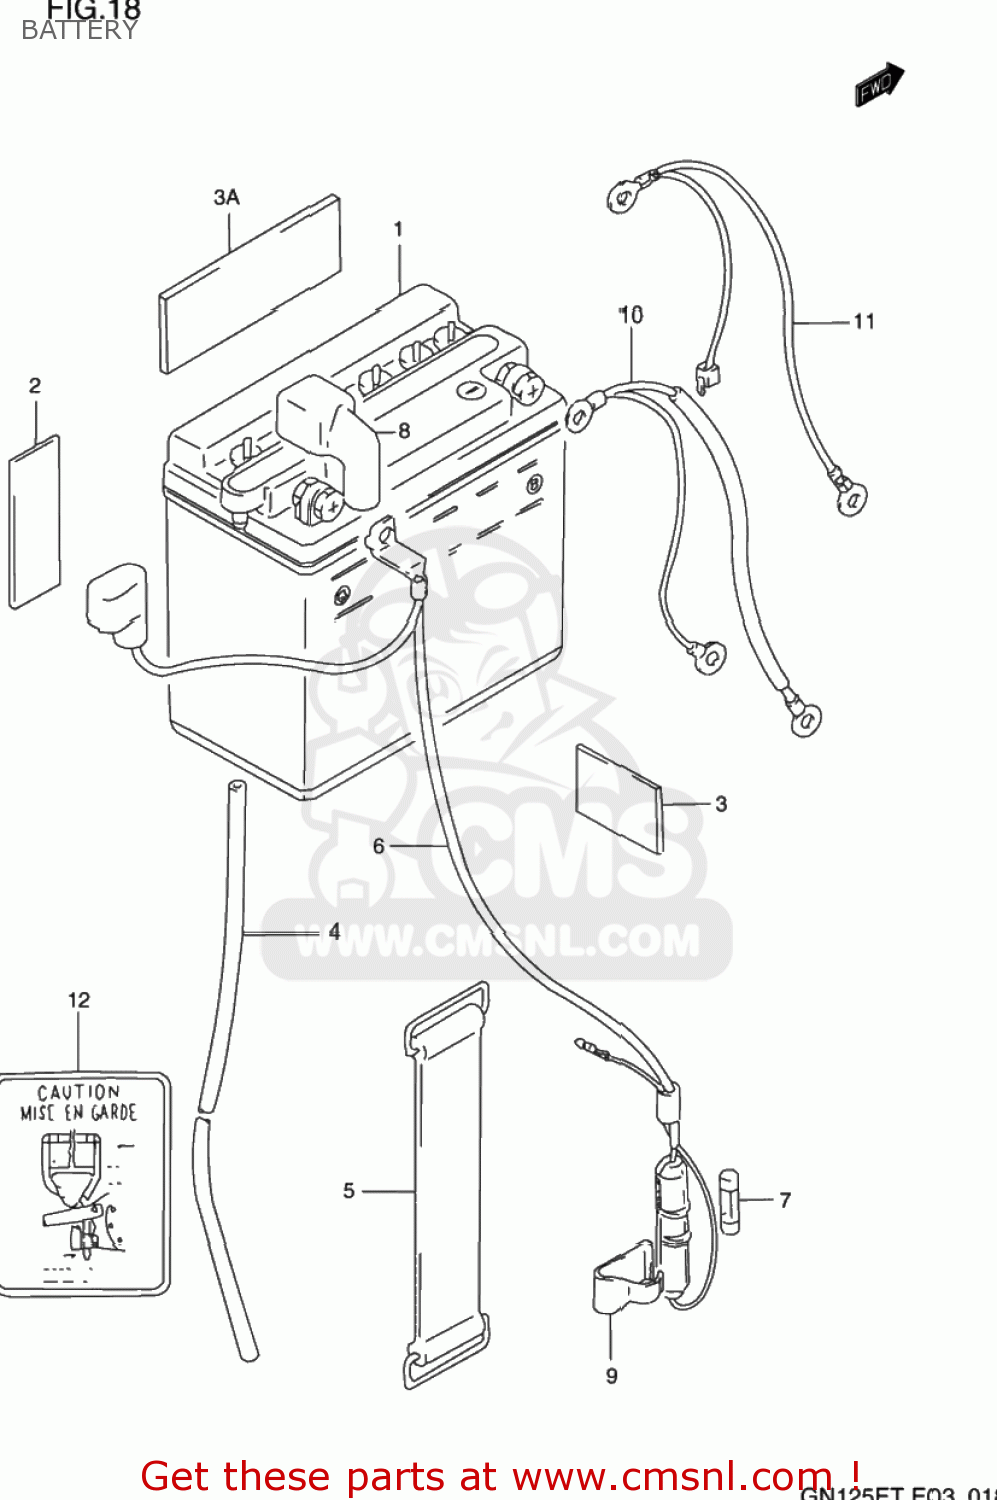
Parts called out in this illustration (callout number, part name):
1	BATTERY ASSEMBLY (12V)
2	PROTECTOR(170X95X3.0)
3	PROTECTOR(170X95X3.0)
3A	CUSHION 20X45X6
4	HOSE,BATTERY EXHAUST
5	BAND
6	FUSE ASSEMBLY,BATTERY PLUS
7	FUSE(15A)
8	CAP,BATTERY PLUS TERMINAL
9	HOLDER,FUSE CASE
10	LEAD WIRE,BATTERY(-)
11	WIRE,BATTERY MINUS LEAD
12	PLATE,BATTERY CAUTION
